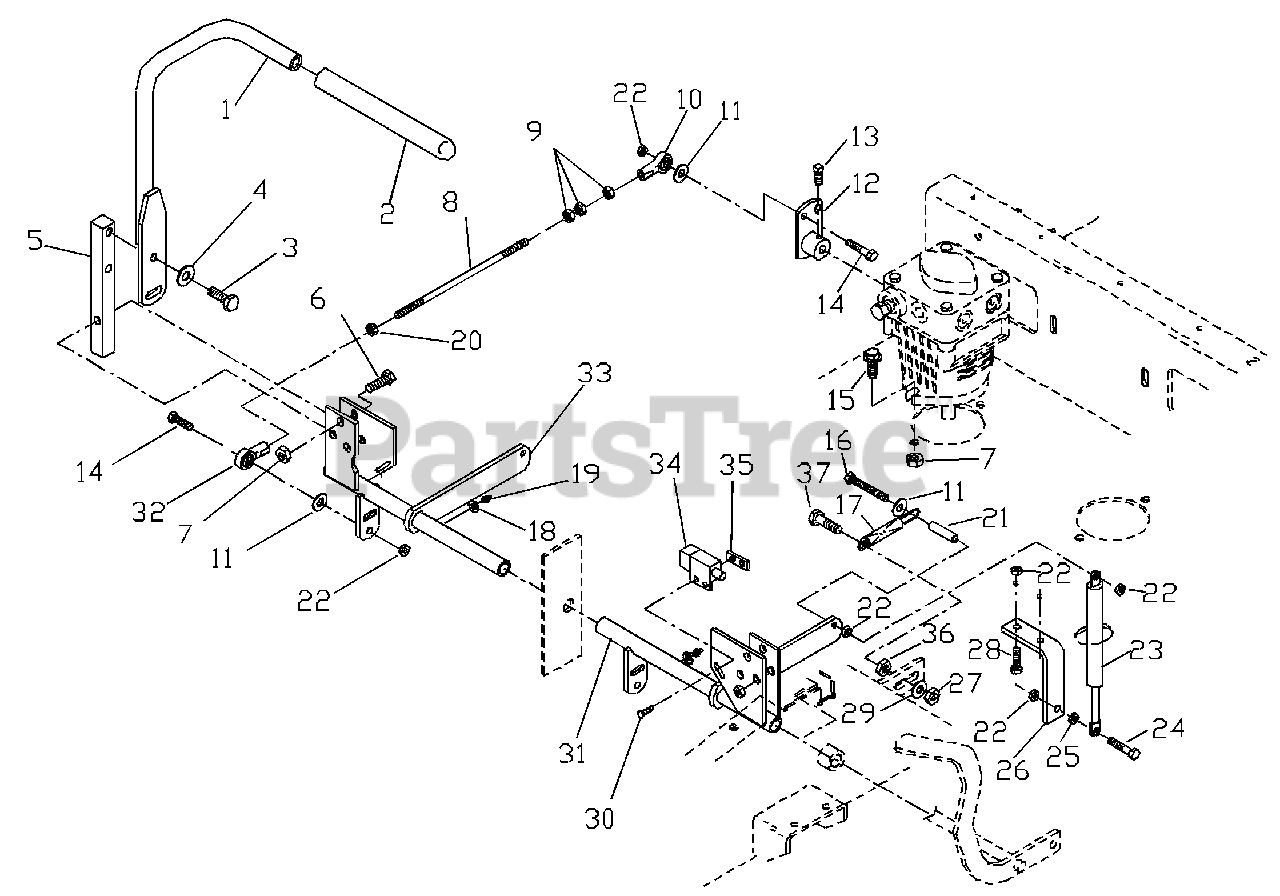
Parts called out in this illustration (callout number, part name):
1	CONT. LEVER
3	HCS 3/8C X 1
4	3/8 SPRING WASHER
5	ARM CONT. SHAFT
6	HCS 3/8C X 1 1/2
7	NUT 3/8C CTR. LOCK
8	PUMP CONTROL LINK
10	BALL JOINT RT.
11	5/16 FLAT WASHER
12	PUMP LEVER
13	5/16C X 5/8 "V" POINT
14	HCS 5/16C X 1
15	HCS 3/8C X 1
16	TAPBOLT 5/16C X 2.25
17	REV. DETENT SPRING
19	ZERK
20	NUT 5/16F LH.
22	5/16C CTR. LOCK
24	HCS 5/16C X 1.25
25	5/16C WHIZ NUT
26	BRACKET "L"
27	3/8C NYLOC
28	HCS 5/16C X 3/4
29	3/8 FLAT WASHER
30	SCREW #10-24 X 5/8
31	CONTROL WLDMT. LEFT
32	BALL JOINT LH.
33	CONTROL WLDMT. RIGHT
35	TAPPED PLATE
36	3/8C WHIZ NUT
37	HCS 3/8C X 2
38	HOSE CLAMP
